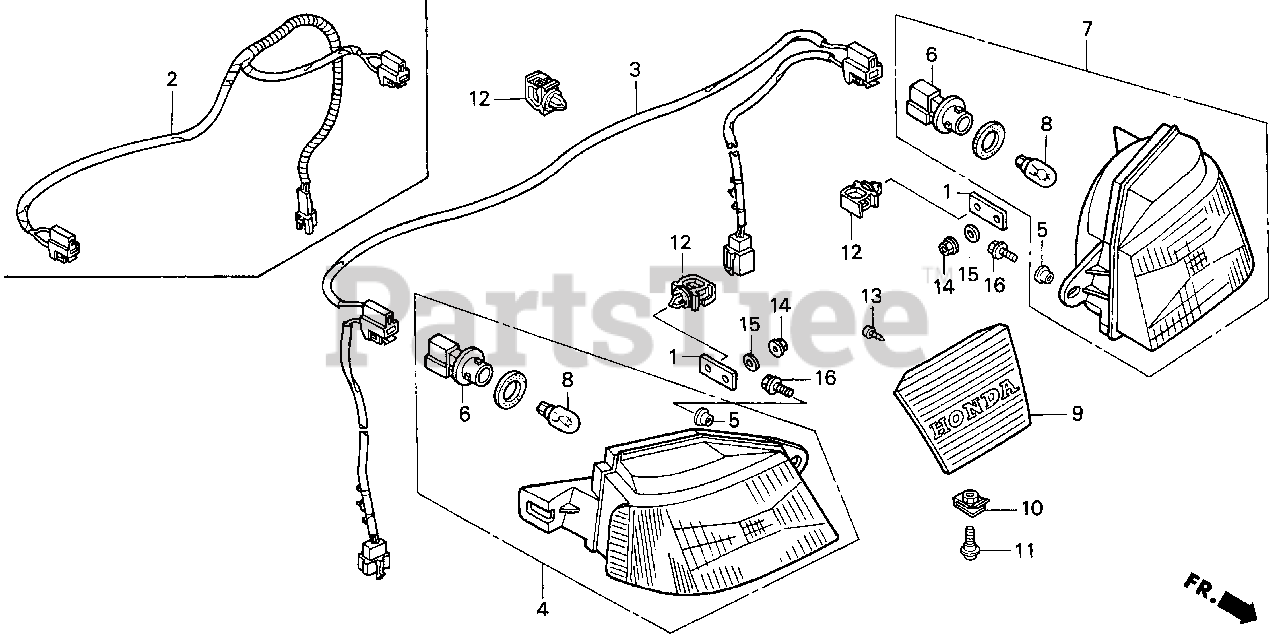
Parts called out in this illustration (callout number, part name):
1	BRACKET, WIRE HARNESS CLIP
3	SUB-WIRE HARNESS, HEADLIGHT
4	HEADLIGHT ASSY., R.
5	SPACER, HEADLIGHT
6	SOCKET ASSY., HEADLIGHT
7	HEADLIGHT ASSY., L.
8	BULB (12V21CP)
9	GARNISH, FR. *NH247* (ASSEMBLY GRAY)
10	NUT, FENDER SETTING
11	SCREW, FR. VISOR
12	CLIP, HARNESS (7MM)
13	SCREW, TAPPING (5X12)
14	NUT, FLANGE (6MM)
16	BOLT, FLANGE (6X16)
